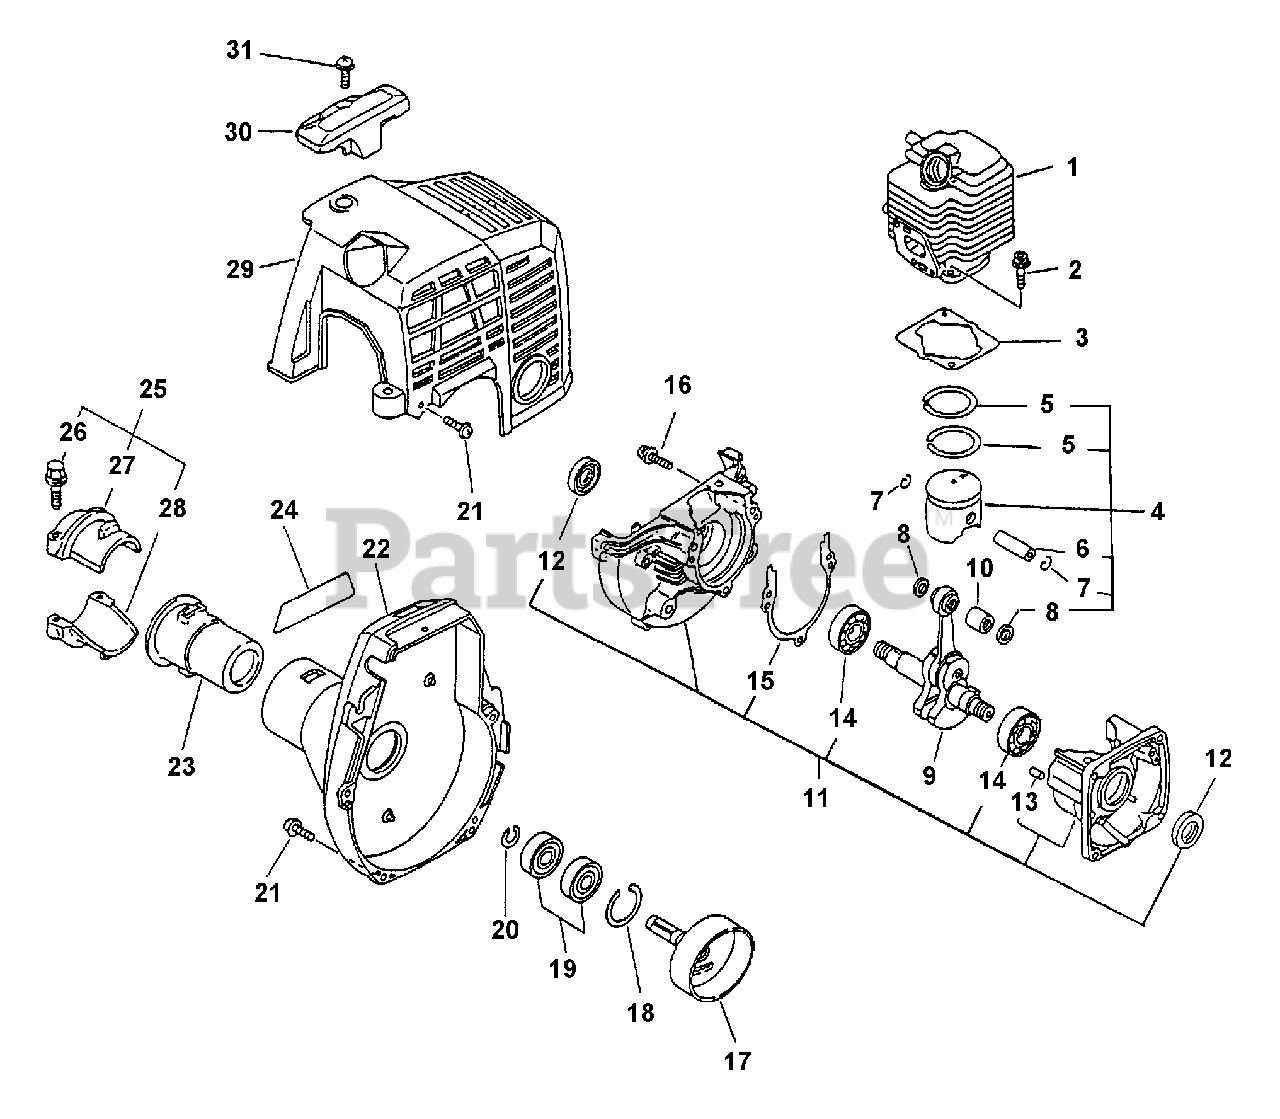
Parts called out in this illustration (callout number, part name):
1	CYLINDER
2	SCREW - 5X22
3	GASKET, CYLINDER
4	PISTON KIT
5	RING, PISTON
6	PIN, PISTON
7	RING, RETAINING
8	SPACER, PISTON
9	CRANKSHAFT ASSY
10	BEARING, NEEDLE
11	CRANKCASE KIT
12	SEAL, OIL
13	PIN - LOCATING
14	BEARING, BALL - 6201
15	GASKET, CRANKCASE
16	SCREW - 5X28
17	DRUM, CLUTCH
18	RING, RETAINING - 28
19	BEARING, BALL - 6001
20	RING, RETAINING - 12
21	SCREW - 4X16
22	CASE, FAN
24	LABEL - MODEL
25	MAIN PIPE CLAMP KIT
26	BOLT - 5X25
27	CLAMP, MAIN PIPE - UPPER
28	CLAMP, MAIN PIPE - LOWER
29	COVER, ENGINE
30	GUARD - TOP
31	SCREW - 5X16
